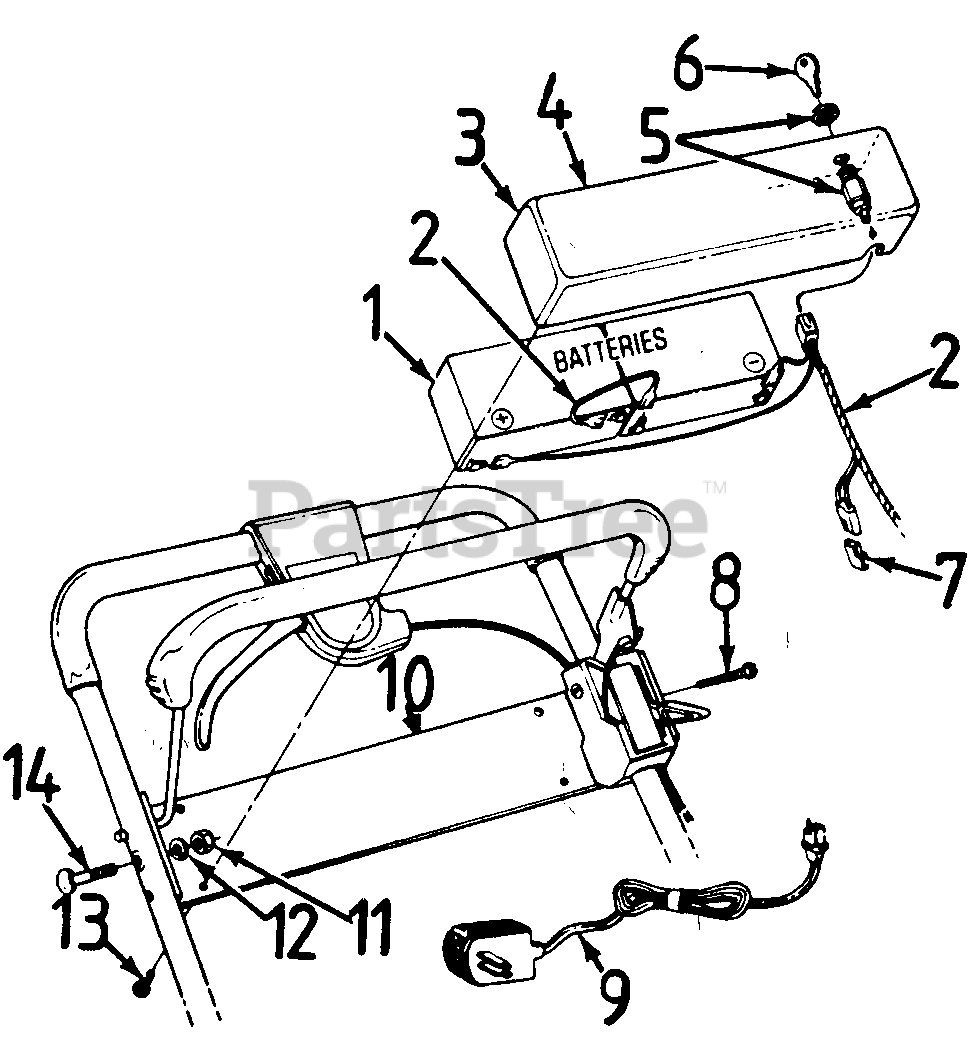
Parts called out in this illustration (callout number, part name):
1	Battery Pack
2	Wire Harness
3	Battery Tray
4	Instruction Label
5	Ignition Switch
6	Ignition Key
7	Plug
8	Truss Mach. Scr. #12 x 1.5" Lg.
9	Battery Charger
10	Lower Battery Tray
11	Hex Nut 5/16-18 Thd.
12	L-Wash. 5/16" I.D.
13	Truss Mach. H-Riser Tap Scr. 1" Lg.
14	Curved Carriage Bolt 5/16-18 x 1.38" Lg.
